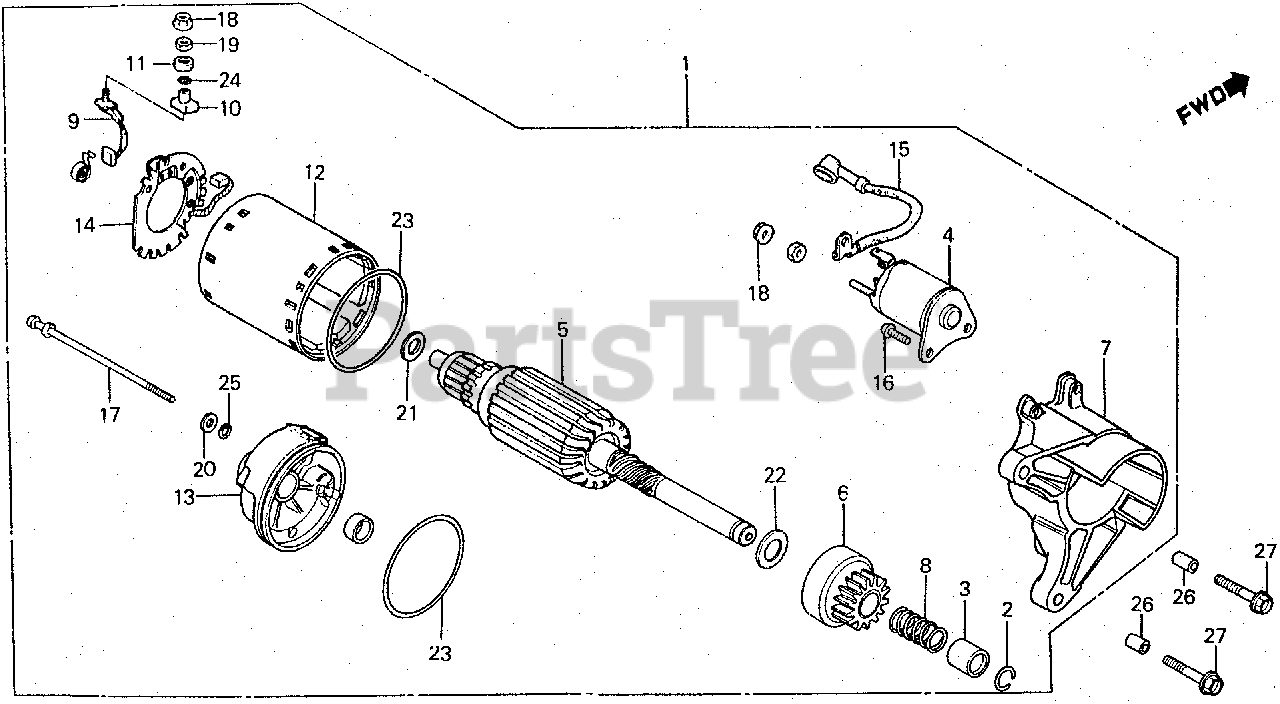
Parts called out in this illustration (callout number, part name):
1	MOTOR ASSY., STARTER
2	RING, SNAP
3	COLLAR, CLUTCH STOP
4	CONTACTOR ASSY.
5	ARMATURE
6	CLUTCH ASSY., OVERRUNNING
7	HOUSING, DRIVE SIDE
8	SPRING, BRUSH
8	SPRING
9	BRUSH
10	BUSHING, INSULATION (NOT AVAILABLE)
10	BUSH, INSULATION
11	BUSHING, INSULATION
11	BUSH, INSULATION
12	YOKE
13	FRAME, STARTER END
14	PLATE, BRUSH HOLDER
15	WIRE, WATER COVER
16	BOLT
17	BOLT, THROUGH (NOT AVAILABLE)
18	NUT
19	NUT
20	WASHER, STEEL PLATE
21	WASHER
22	WASHER
23	O-RING
24	O-RING
25	O-RING
26	PIN, DOWEL (10X16)
27	BOLT, FLANGE (8X35)
